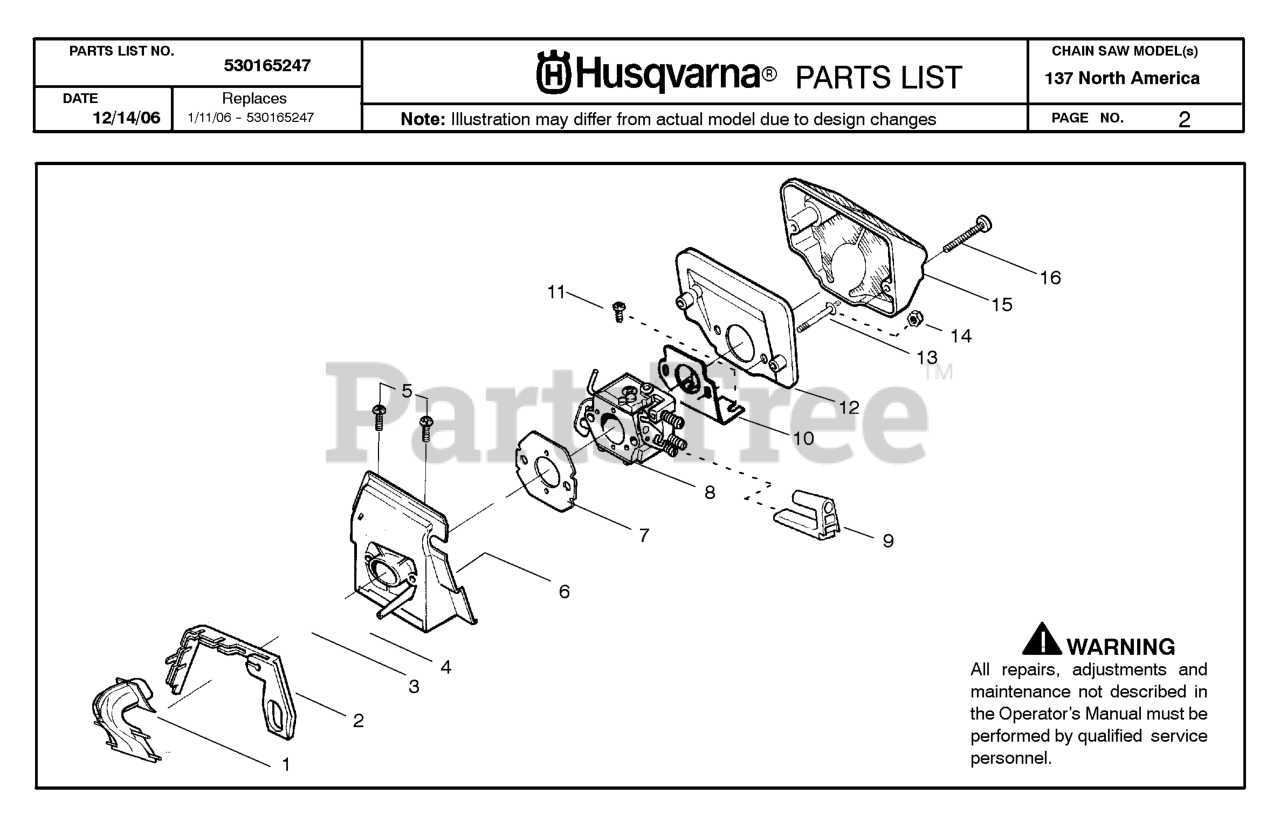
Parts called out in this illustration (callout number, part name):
1	INTAKE HORN
2	TURBO CLEAN SEAL
3	INTAKE PIPE
4	IMPULSE PIPE
6	CARB ADAPTOR
7	GSKT,CARB 36/41
8	CARBURETOR W-29
12	AIR FILTER (BOTTOM)
13	STUD-CARBURETOR
15	AIR FILTER
